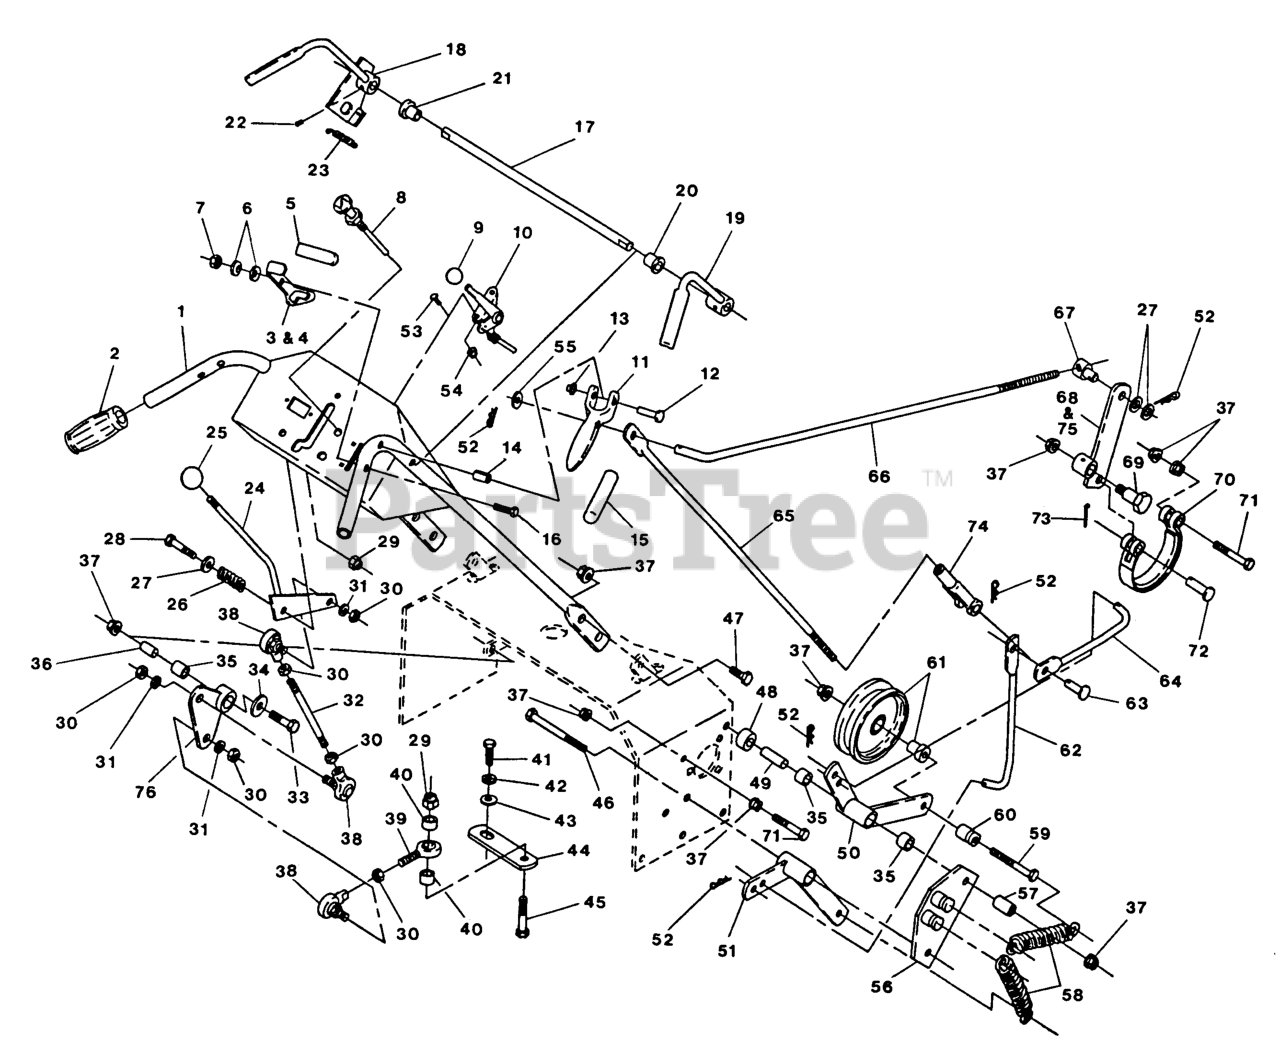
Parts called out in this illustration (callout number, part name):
5	GRIP-LATCH
6	WASHER-SPRING
7	NUTTORQUE ZNKPLT
8	CONTROL-CHOKE
9	KNOB-BALL
12	PIN-LEVER, DRIVE
13	NUT-PUSH
14	PIN-ROLL
15	GRIP-LEVER, DRIVE
17	ROD,CONNECTING
20	BUSHING-NYLON
21	BUSHING,FLANGED
23	SPRING-EXTENSION
25	KNOB-BALL
31	WASHER-LOCK
35	SLEEVE-BEARING
38	BALLJOINT
40	SPACER-PLATED
42	WASHER-LOCK
49	BUSHING-PIVOT, IDLER
52	PIN-COTTER
53	BOLT-CARR
58	SPRING-EXTENSION
60	ANCHOR-SPRING PLTD
61	KIT,48 RH IDLER/BUS
63	PIN-CLEVIS
66	LINKAGE,BRAKE
67	SWIVEL,SHORT ADJUSTING
69	BOLT-SHOULDER
74	YOKE-ADJUSTABLE
